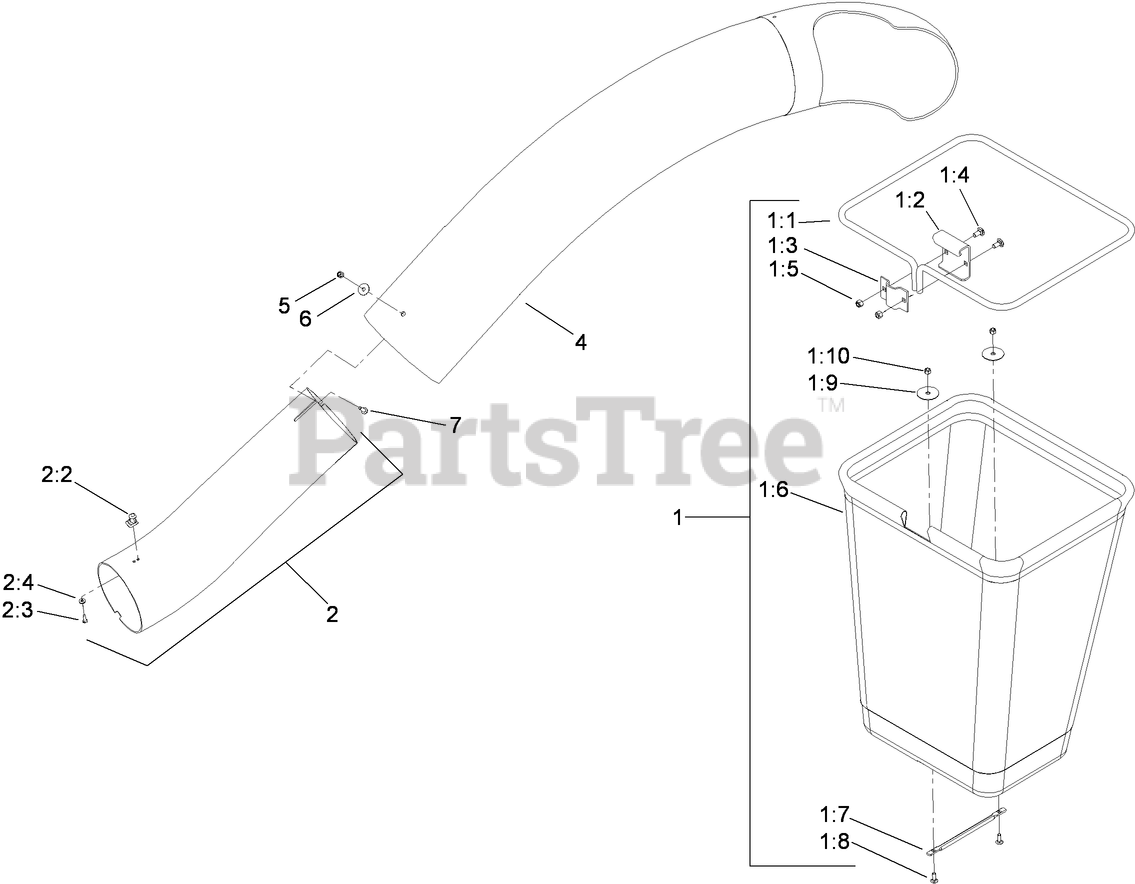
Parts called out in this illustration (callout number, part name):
1	BAG AND FRAME ASM
1:1	FRAME-BAG
1:2	HANGER-BAG
1:4	BOLT-CARR
1:5	NUT-LOCK, NI
1:6	BAG ASM
1:7	HANDLE-BAG
1:8	BOLT-CARR
1:9	WASHER
1:10	NUT-LOCK, NI
2	LOWER TUBE ASM
2:2	LATCH-KEEPER
2:3	SCREW-PPH
2:4	WASHER-FLAT
4	TUBE-UPPER
5	NUT-LOCK, NI
6	WASHER-FLAT
7	SCREW-HWH
